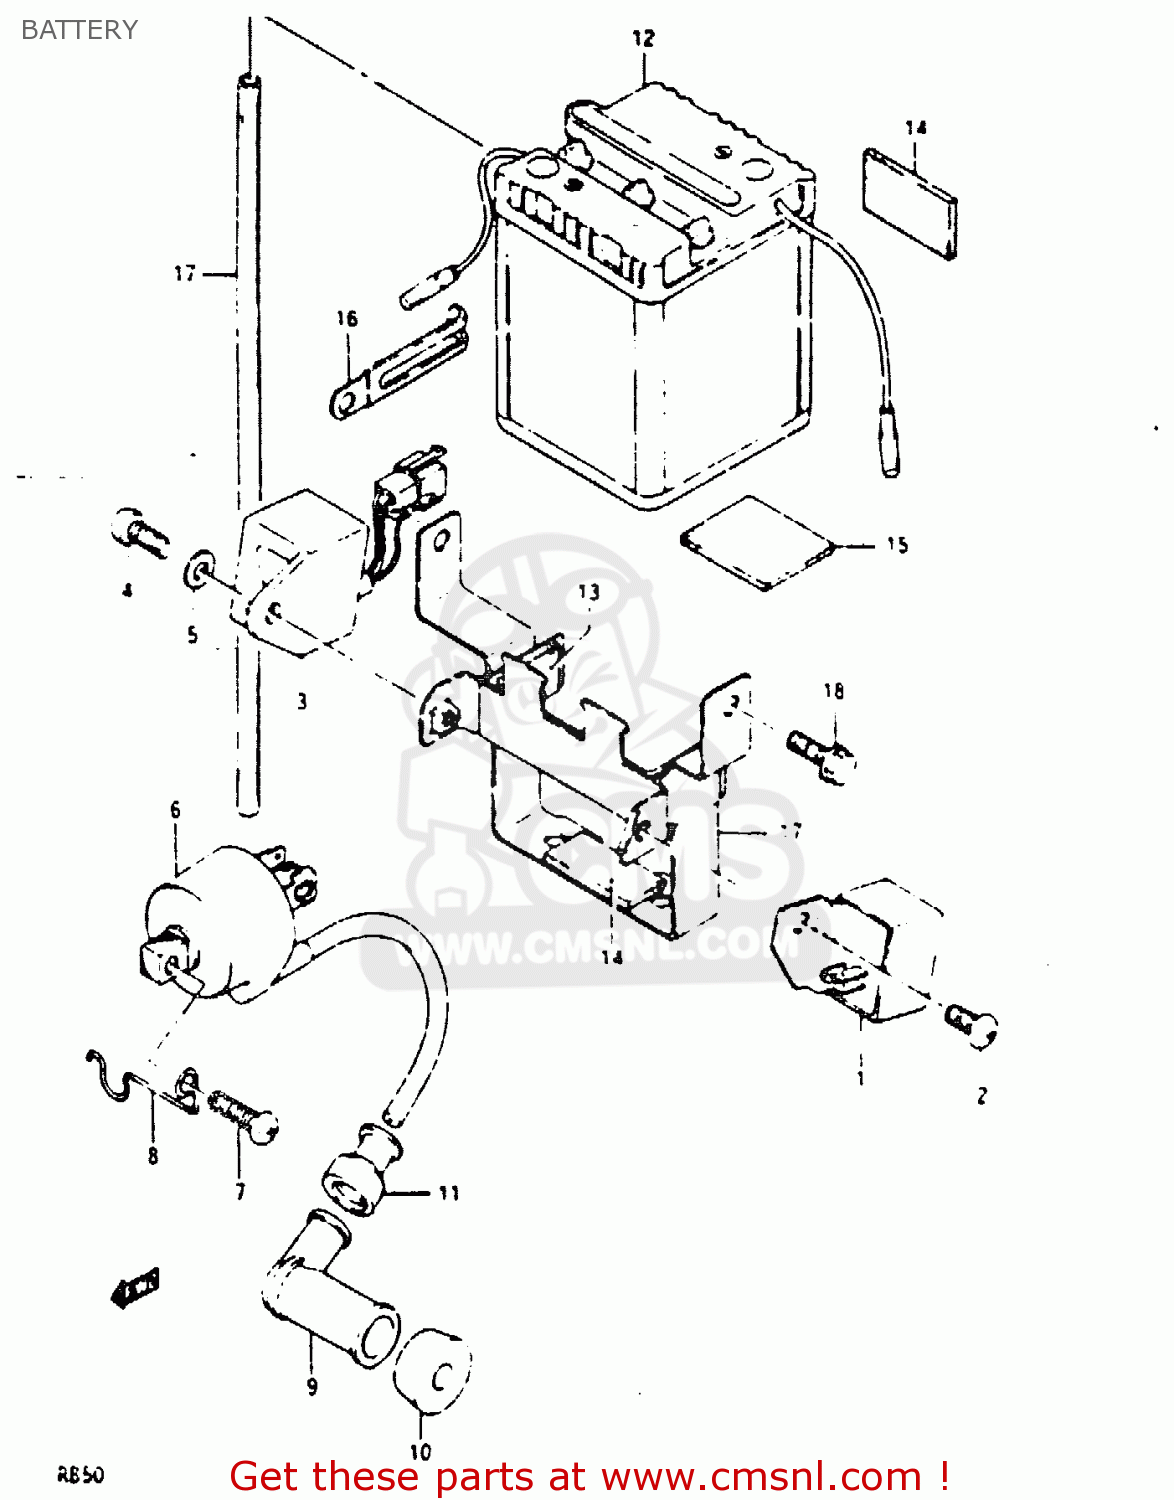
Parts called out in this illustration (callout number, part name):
1	RECTIFIER ASSEMBLY
2	SCREW
3	CDI UNIT
4	SCREW
5	WASHER, LOWER
6	COIL ASSEMBLY,IGNITION
7	SCREW
8	GUIDE,CLUTCH CABLE
9	CAP ASSY,SPARK PLUG
10	SEAL,SPARK PLUG CAP
11	SEAL,SPARK PLU
13	PROTECTOR,BATTERY
14	PROTECTOR,BATTERY
15	PROTECTOR(170X95X3.0)
16	CLAMP
17	HOLDER,BATTERY
18	BOLT
